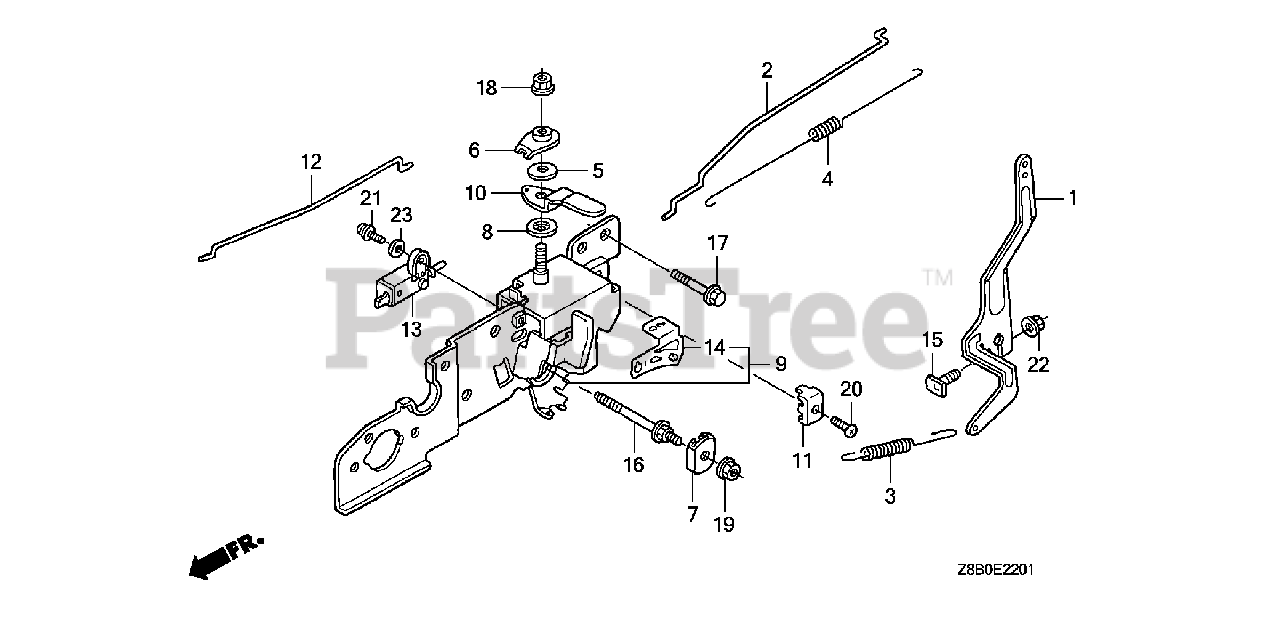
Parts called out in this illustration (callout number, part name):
1	ARM, GOVERNOR
2	ROD, GOVERNOR
3	SPRING, GOVERNOR
4	SPRING, THROTTLE RETURN
5	SPRING, LEVER
6	WASHER, CONTROL LEVER
7	PLATE, LEVER CENTER
8	SPACER, CONTROL LEVER
9	BASE, CONTROL
10	LEVER, CHOKE
11	HOLDER, CABLE
12	ROD, CHOKE
13	SWITCH ASSY., ENGINE STOP (N.O)
14	MARK, THROTTLE INDICATION
15	BOLT, GOVERNOR ARM
16	BOLT, SPECIAL (6X45)
17	BOLT, FLANGE (6X32)
18	NUT, SELF-LOCK (6MM)
19	NUT, SELF-LOCK (5MM)
20	SCREW, PAN (5X16)
21	SCREW-WASHER (4X12)
22	NUT, FLANGE (6MM)
23	WASHER, PLAIN (4MM)
